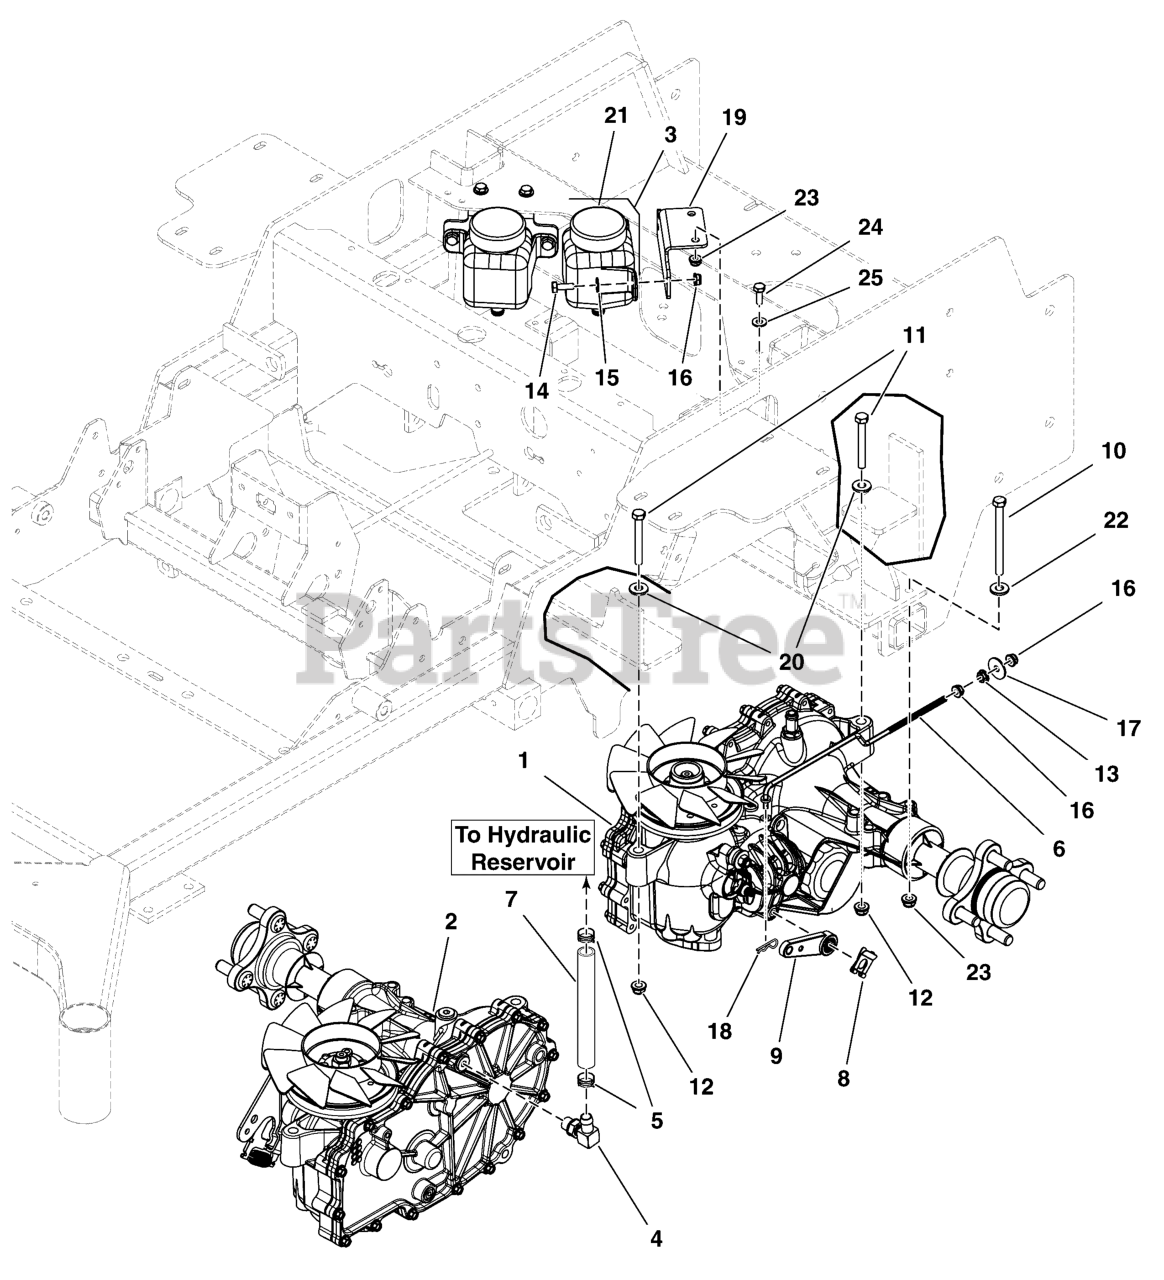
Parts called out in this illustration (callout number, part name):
1	TRANSAXLE, ZT3200, LH, ZJ-KYEF-8T7C-1GRX
1	TRANSAXLE, ZT-3200, LH,ZJ-KYEF-9T7C-1GRX
2	TRANSAXLE, ZT3200, RH, ZJ-GYEF-8T7B-1GRX
2	TRANSAXLE, ZT-3200, RH,ZJ-GYEF-9T7B-1GRX
3	RESERVOIR, HYDRO OIL, 350 ML
4	FITTING, 9/16 O-RING-1/2" HOSE, 90 DEG
5	CLAMP, HOSE, .75 FREE DIA.
6	ROD, DUMP VALVE, S125XT, CZ
7	HOSE, 1/2" X 5.5" PUSH LOCK
8	E-CLIP, BRAKE ARM, ZT3100 & ZT3400
9	BRAKE ARM, ZT3400
10	BOLT, 5/16-18 X 3" GD5 YZ
11	BOLT, 3/8-16 X 2-1/2" GD5 CZ
12	NUT, 3/8 - 16 HEX NYLOCK FLANGE
13	NUT, 1/4-20 HEX SERR. FLANGE
14	BOLT, 1/4"-20 X 3/4" GD5 YZ
15	WASHER, 1/4 SAE
16	NUT, 1/4-20 Hex Nylock Flange
17	WASHER, 1/4" Fender
18	PIN, HAIR, .0585 X 1-1/8, 1/4 EYE, YZ
19	PLATE, HYDRO BOTTLE, TALL MOUNT- BLK
20	WASHER, 3/8 SAE
21	RESERVIOR CAP
22	WASHER, 5/16 GRADE 9, FLAT
23	NUT, 5/16-18 HEX NYLOCK FLANGE NUT
24	BOLT, 5/16-18 X 1" GRD5 YZ
25	WASHER, 5/16" SAE
